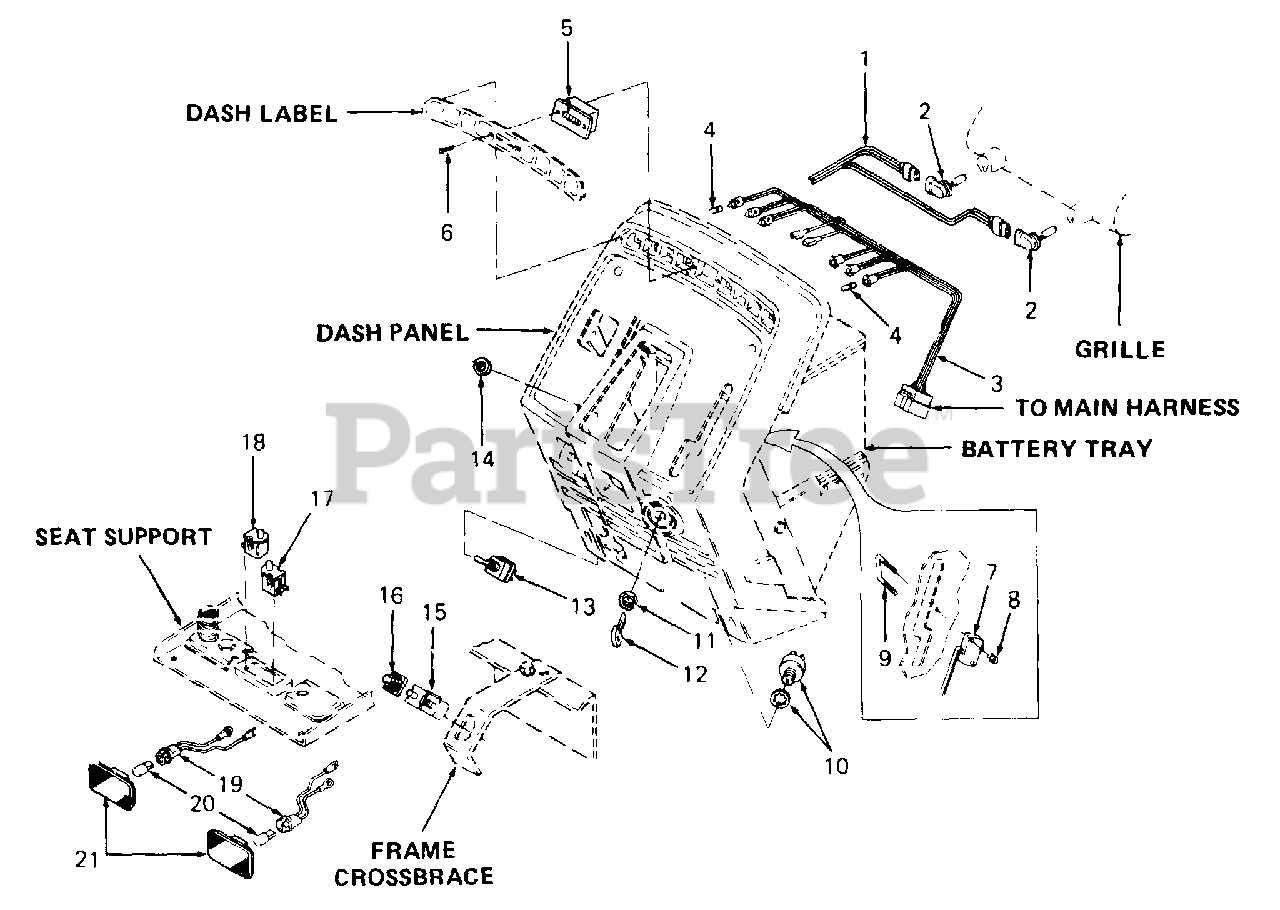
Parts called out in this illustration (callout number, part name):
1	Harness, Main Wire
2	Bulb, Head Lamp
3	Harness, Indicator Wire
4	Bulb, Indicator
5	Hour Meter
6	Screw, Truss Hd Tapp, #6 X .62 Lg
7	Switch, Reverse
8	Nut, Hex Insert Lock, #4-40
9	Screw, Switch
10	Switch, Ignition
11	Nut, Ignition Switch
12	Key, Ignition (Set of 2)
13	Switch, PTO
14	Nut, Hex, 1/2-27 X.100 Thk
15	Switch, Interlock
16	Boot, Switch
17	Switch, Snap Mount Normally Closed (Grey)
18	Switch, Snap Mount Normally Open (Black)
19	Cable Assy, Tail Light
20	Bulb, Tail Light
21	Lens Assy Tail Light
